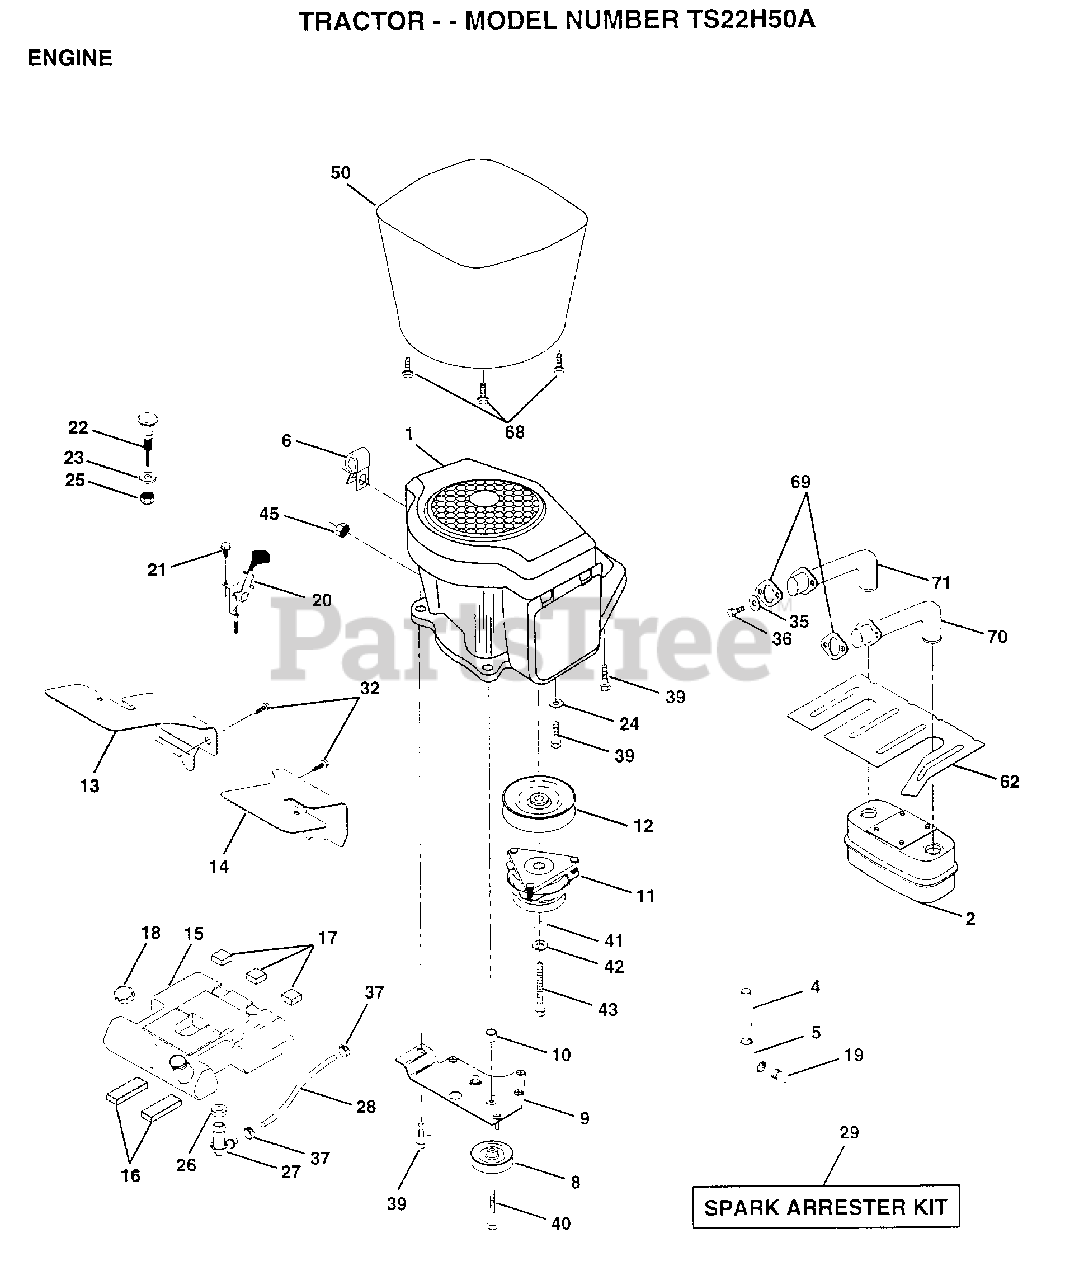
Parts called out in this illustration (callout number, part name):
1	ENGINE ONAN
2	MUFFLER ASM-ONAN
5	ELBOW
6	CLAMP.TUBE.DBL.EN
10	BUSHING.
12	PULLEY.ENGINE.VGT
13	"BAFFLE-LF,ONAN"
14	BAFFLE-RH.ONAN
15	TANK FUEL REAR
16	PAD IDLER TI
17	PAD-SPACER LT
18	CAP ASM FUEL
19	PLUG T
21	SCREW LT
23	WASHER
24	LOCKWASHER
25	"NUT,KEPS 3/8-24IM"
26	BUSHING OUTLET T
27	STEM.TANK.FUEL
29	SPARK ARREST KIT
32	SCREW LT
35	LOCKWASHER
36	SCREW
37	HOSE CLAMP
39	SCREW LT
40	SCREW.3/8-16X3.25
41	WASHER
42	LOCKWASHER
43	BOLT.7/16-20X4.25
45	NUT FLANGE M8-125
50	"DUCT-AIR,ONAN,YP"
62	"SHIELD-HEAT,ONAN"
64	SCREW
65	WASHER
67	SCREW
68	"SCREW-TT,10-32 FL"
69	GASKET-MUFFLER )
70	"PIPE-EXHAUST,LH"
71	PIPE EXHUST RH
